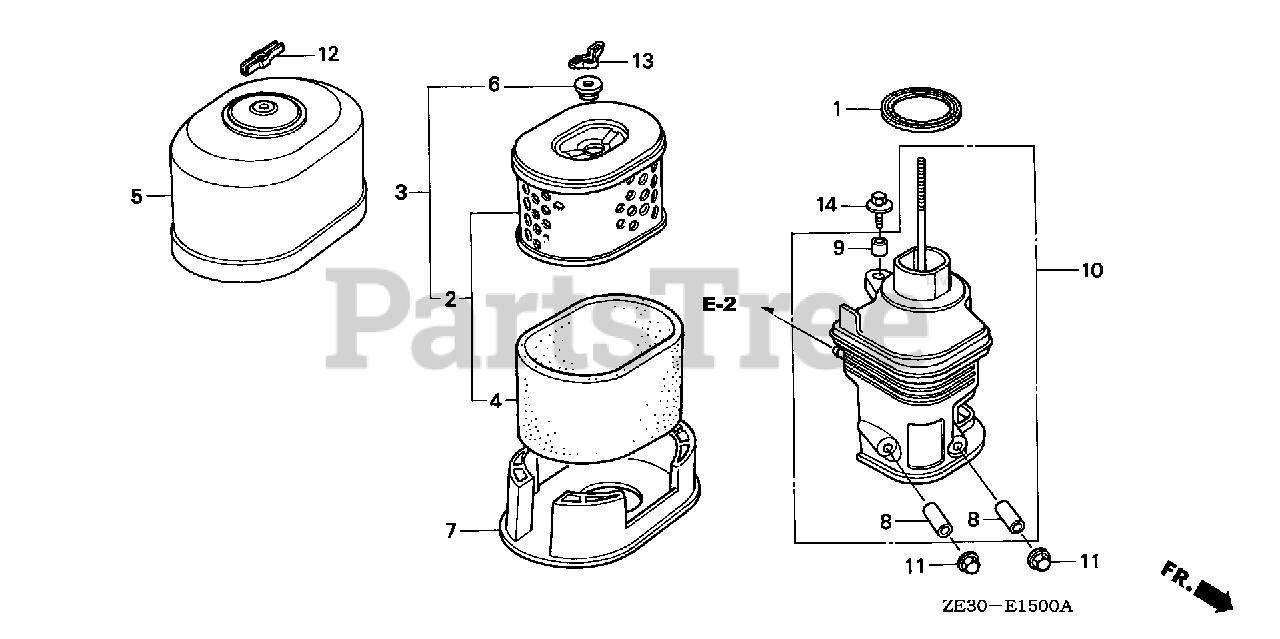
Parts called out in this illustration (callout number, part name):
1	GASKET, ELBOW
2	ELEMENT, AIR CLEANER
3	ELEMENT, AIR CLEANER
4	FILTER (OUTER)
5	COVER, AIR CLEANER (STD)
6	GROMMET, AIR CLEANER
7	NOSE, MUFFLER
8	COLLAR, AIR CLEANER
9	COLLAR B, AIR CLEANER
10	ELBOW, AIR CLEANER
11	NUT, CAP (6MM)
12	NUT, AIR CLEANER COVER (DACRO COATING)
13	NUT, TOOL BOX SETTING
14	BOLT-WASHER (6X20)
